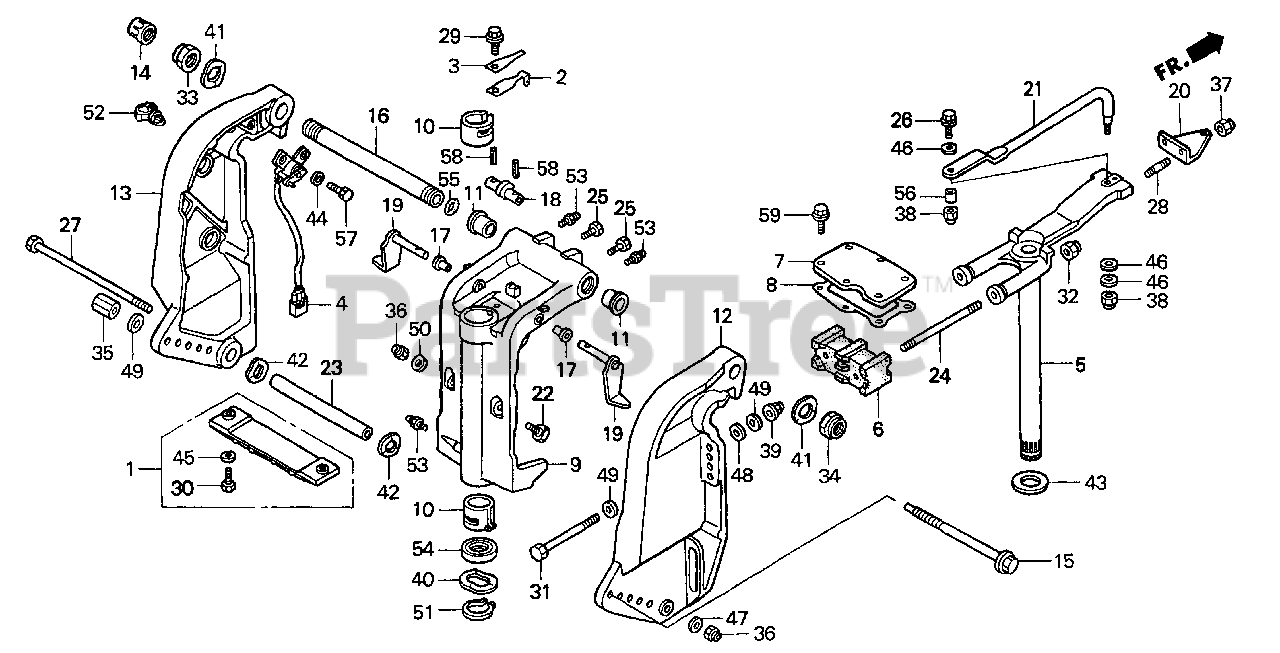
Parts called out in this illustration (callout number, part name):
1	METAL KIT, ANODE
2	SPRING, CLICK
3	SPRING, CLICK ASSIST
4	SENSOR ASSY., TRIM ANGLE
5	FRAME, MOUNTING *NH282MU* (OYSTER SILVER METALLIC-U)
5	FRAME, MOUNTING
6	MOUNT, RUBBER (UPPER)
7	HOLDER, MOUNTING (UPPER)
8	GASKET, MOUNTING HOLDER (UPPER)
9	CASE, SWIVEL *NH282MU* (OYSTER SILVER METALLIC-U)
10	LINER, SWIVEL CASE
11	BUSH, SWIVEL CASE
12	BRACKET, R. STERN *NH282MU* (OYSTER SILVER METALLIC-U)
13	BRACKET, L. STERN *NH282MU* (OYSTER SILVER METALLIC-U)
14	CAP, TILTING BOLT
15	ROD, ADJUSTING
16	SHAFT, TILTING
17	BUSH, TILT ARM
18	BRACKET, TILTING
19	STOPPER, TILT
20	PLATE, STEERING
21	ROD, STEERING
22	RECEIVER, THRUST
23	COLLAR, CYLINDER (LOWER)
24	BOLT, STUD (12X150)
25	BOLT (1/4-28UNF)
26	BOLT (3/8-24UNF)
27	BOLT, HEX. (10X235)
28	BOLT, STUD (10X28)
29	BOLT, HEX. (6X14)
30	BOLT, HEX. (6X25)
31	BOLT, HEX. (12X119)
32	NUT, FLANGE (12MM)
33	NUT, SELF-LOCK (7/8-14UNF)
34	NUT, SELF-LOCK (M25X2.0)
34	NUT, SELF-LOCK (25X2.0)
35	NUT, ADJUSTER ROD
36	NUT, SELF-LOCK (10MM)
37	NUT, SELF-LOCK (10MM)
38	NUT, SELF-LOCK (3/8-24UNF)
39	NUT, SELF-LOCK (12MM)
40	WASHER, WAVE (40MM)
41	WASHER, WAVE (26MM)
42	WASHER, WAVE (32MM)
43	WASHER, THRUST (34MM)
44	WASHER, PLAIN (6MM)
45	WASHER, PLAIN (6MM)
46	WASHER (10MM)
47	WASHER, PLAIN (10MM)
48	WASHER, PLAIN (12MM)
49	WASHER, PLAIN (12MM)
50	WASHER, PLAIN (10MM)
51	CIRCLIP (OUTER) (39MM)
52	CLIP, WIRE HARNESS
53	NIPPLE, GREASE
54	OIL SEAL (39.5X52X6) (ARAI)
55	O-RING (15.54X2.26)
56	COLLAR, STEERING ROD
57	BOLT, HEX. (6X20)
58	PIN, SPRING (2.5X20)
59	BOLT, FLANGE (8X35)
